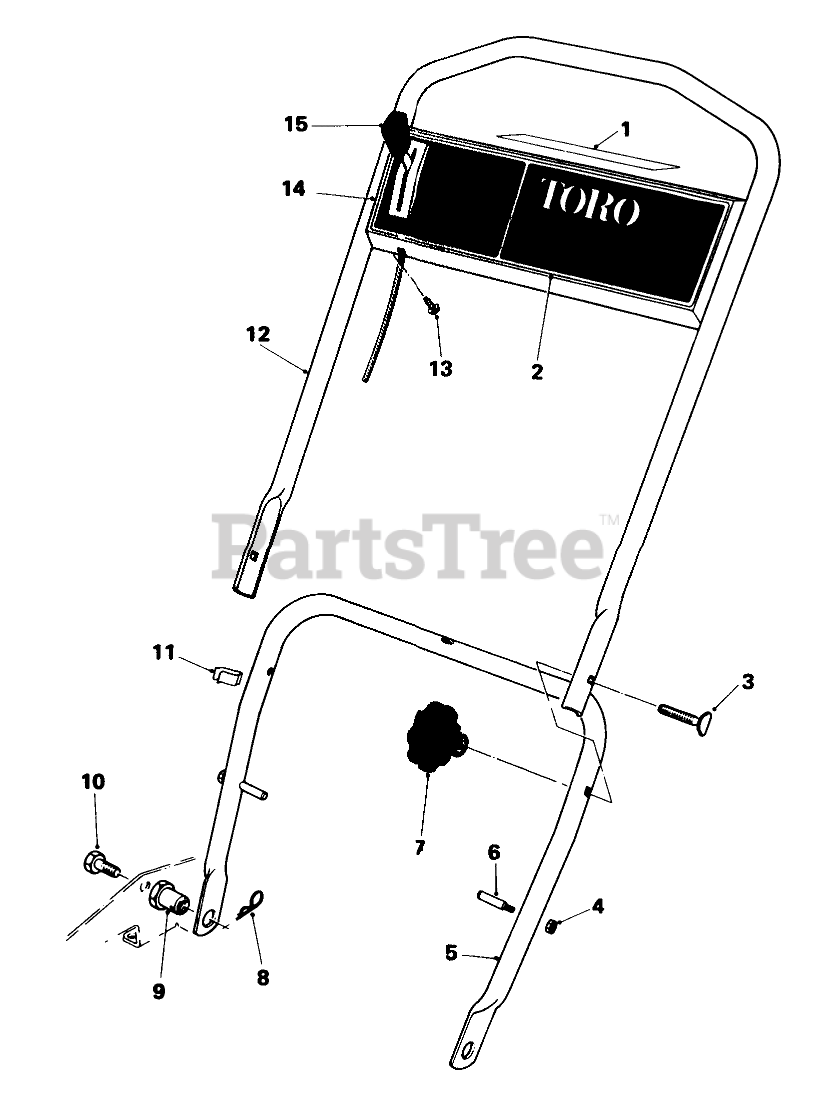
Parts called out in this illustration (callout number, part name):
1	Decal-Instruction
2	Decal-Control Plate
3	SCREW-HANDLE
4	Nut
5	LOWER HANDLE
6	HANDLE PIN
8	PIN-COTTER, HAIR
9	HANDLE PIVOT NUT
10	SCREW-HH
12	UPPER HANDLE
13	SCREW-HWHTF
14	Control Plate
15	Throttle Control
